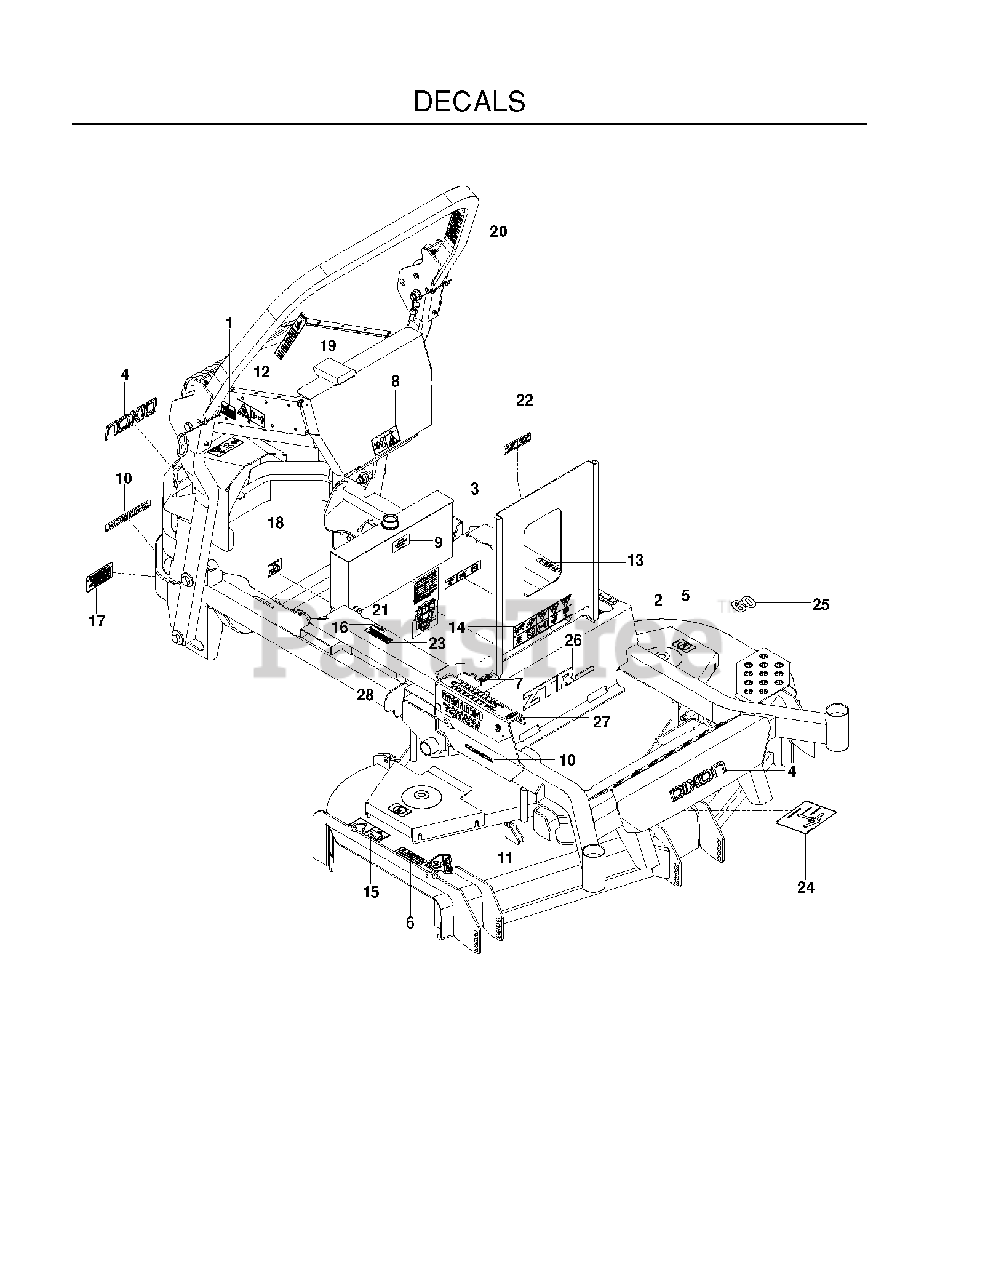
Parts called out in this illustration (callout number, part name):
1	DECAL, DEBRIS SCREEN
2	DECAL, MOTION CONTROL
3	DECAL, BATTERY
5	DECAL, NO STEP
6	DECAL, CAUTION
7	DECAL, TRACKING
8	DECAL, BELT DRIVE
9	DECAL, OIL TANK
10	DECAL, COMMERCIAL
11	DECAL, CPSC
12	DECAL, HOT
13	DECAL, PARK BRAKE
14	DECAL, WARNING
15	DECAL, EURO SEVERING
16	DECAL, ECM, AUSTRALIA
17	DECAL, PROP. 65
19	DECAL, ROPS, WARNING
20	DECAL, ROPS, DIESEL
21	DECAL, SERVICE, DIESEL
22	DECAL, FUSE, DIESEL
23	DECAL, WARNING SPARK ARRESTOR
24	DECAL, BELT ROUTING
26	DECAL, DX200
